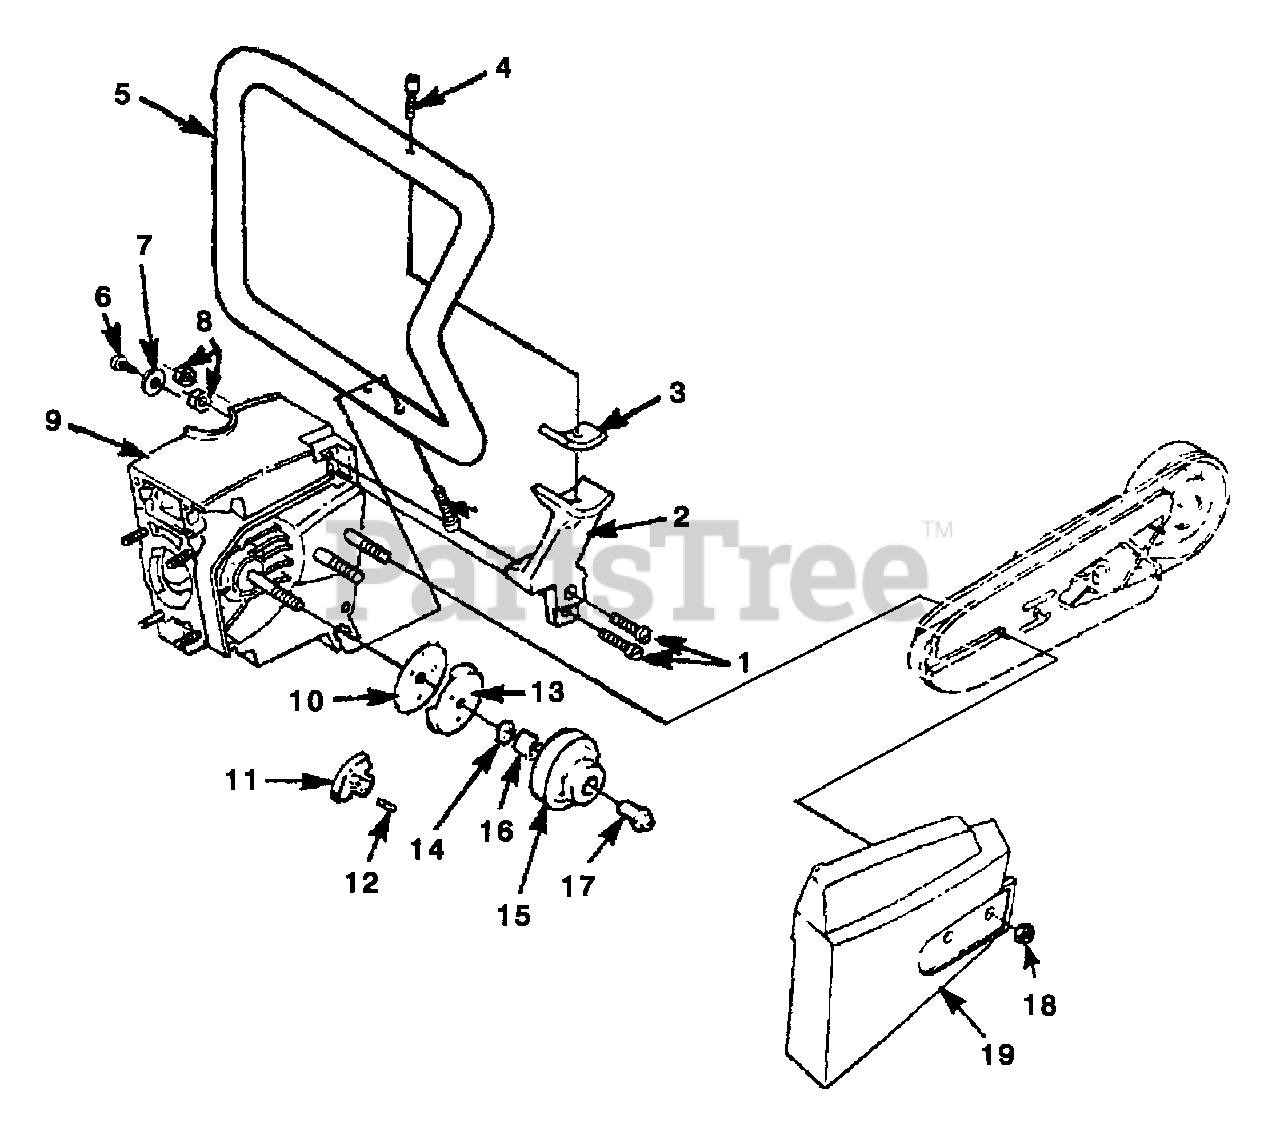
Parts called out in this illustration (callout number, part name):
1	SCREW - Hex hd (12-24 X 7/8")
2	BRACKET - Handle bar
3	MOUNT - Shock (bracket)
4	SCREW - Nylock (1/4-20 X 1")
5	HANDLE BAR
6	SCREW - Pan hd
8	NUT - Hex 12-24
9	CRANKCASE
10	COVER - Clutch
11	CLUTCH ASSEMBLY
12	SPRING - Clutch
13	PLATE - Clutch
14	WASHER - Thrust (Inner)
15	PULLEY - Bearing & Arm
16	BEARING - Needle
17	INNER RACE KIT
18	NUT - Hex Flange (5/16-18)
19	COVER - Drivecase
